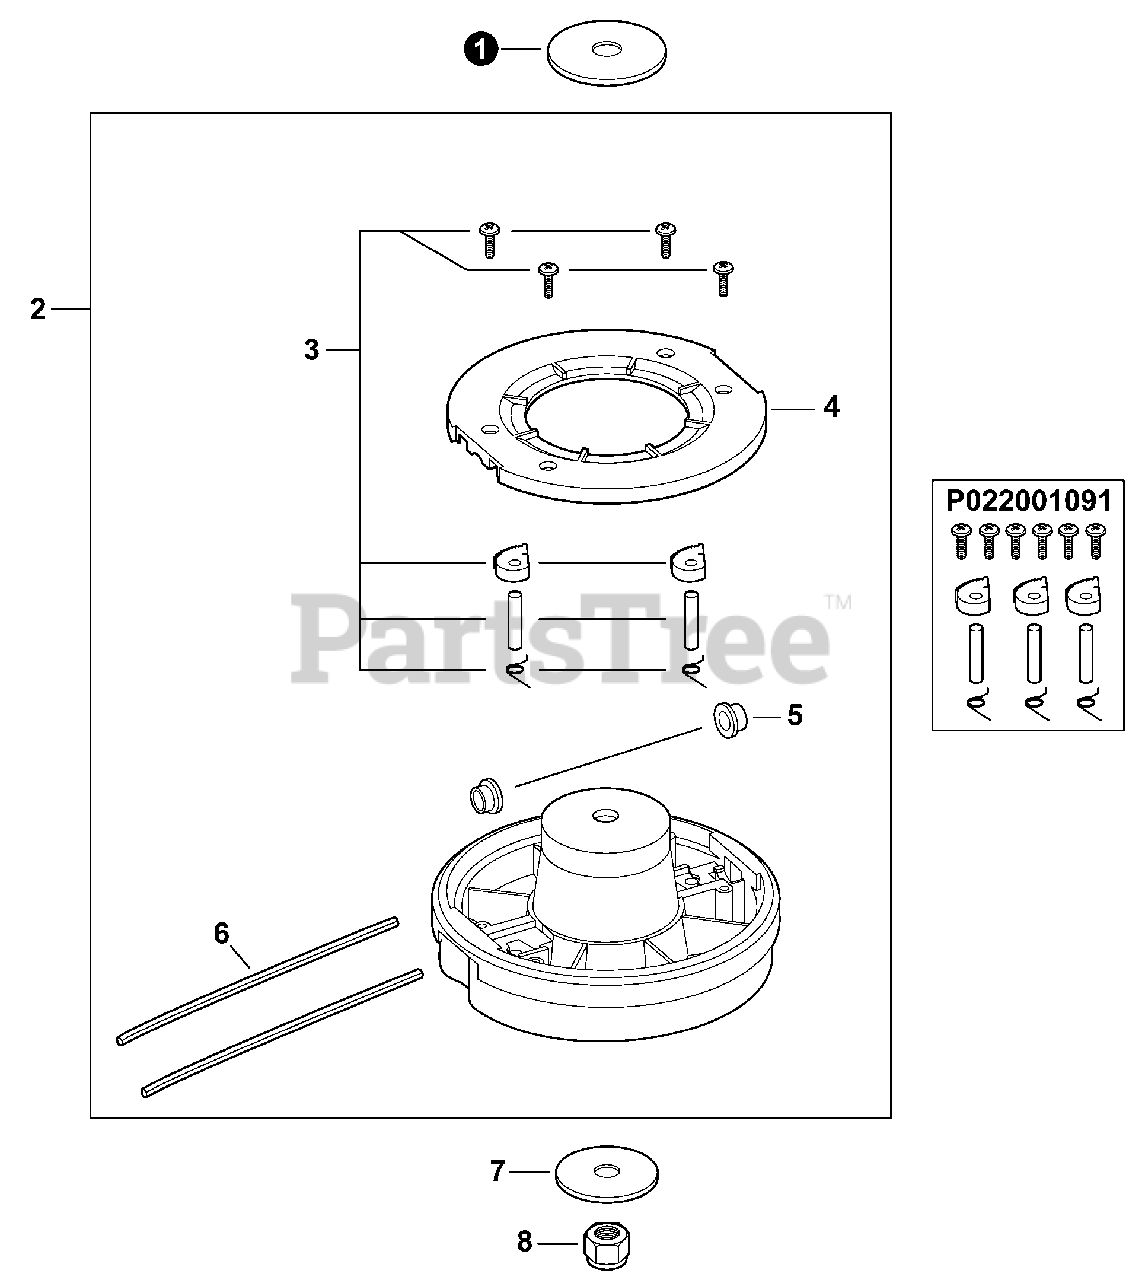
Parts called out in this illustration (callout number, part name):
2	TRIMMER HEAD, RAPID-LOADER - 2 LINE
3	PAWL KIT
4	COVER, TOP
5	EYELET (PACKAGE OF 3)
6	LINE, TRIMMER - 0.095 DIA. (PKG. OF 20)
7	WASHER 10
8	NUT, LOCK
